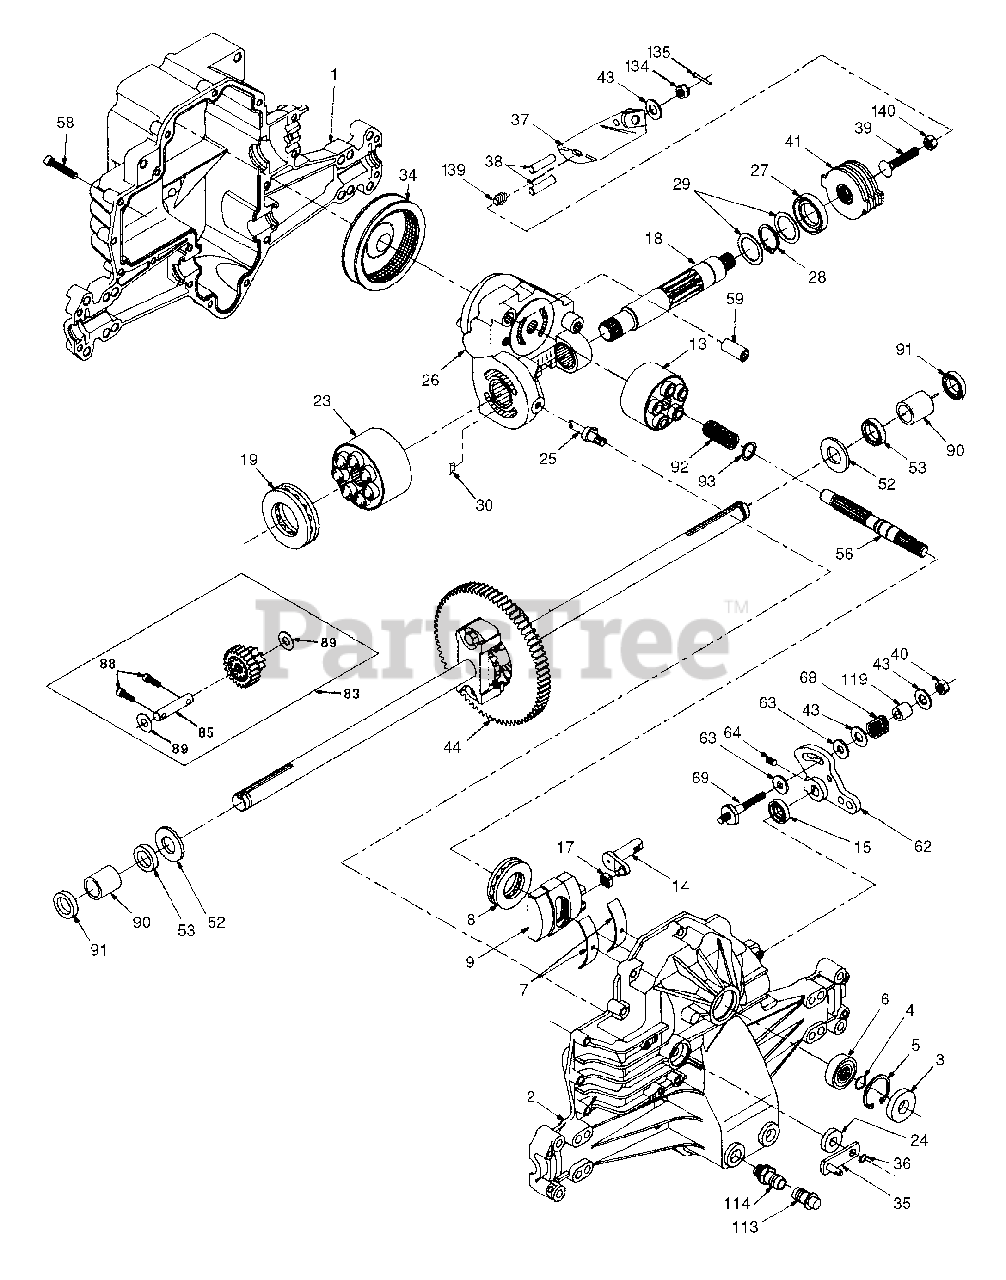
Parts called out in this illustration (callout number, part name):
1	Housing, Lower
2	Assembly, Upper Housing
3	Seal, Lip
4	Ring, Wire Retaining
5	Ring, Retaining
6	Bearing, Shaft Ball
7	Bearing, Cradle
8	Bearing, Thrust 30 x 52 x 13
9	Swashplate, Variable
13	Block, Cylinder Assembly
14	Arm, Trunnion
15	Seal, Lip
17	Guide, Slot
18	Shaft, Motor
19	Bearing, Thrust 42 x 68 x 16
23	Block, Cylinder Assembly
24	Seal, Lip 10 x 25 x 7
25	Actuator, Bypass
26	Center Section Assembly Kit
27	Seal, Lip 26 x 42 x 8
28	Ring, Retaining
29	Washer 26 x 35 x 1
30	Plate, Bypass
34	Oil Filter Element
35	Arm, Bypass
36	Ring, Retaining
37	Arm, Actuating
38	Pin, Actuating
39	Bolt 5/16-24 x 1-3/4
40	Locknut, Hex 5/16-24 UNJC
41	Brake Rotor/Stator Kit
43	Washer 7/16 x 7/8 x .060
44	Differential Assembly
52	Washer 3/4 x 1.5 x .13
53	Seal .75 x 1.25 x .250
56	Shaft, Input
58	Bolt 1/4-20 x 1.38
59	Pin .5 OD x .43 ID x .750
62	Arm, Control
63	Puck, Dampener
64	Set Screw
68	Spring
69	Stud 5/16-24
83	Jackshaft Assembly
85	Jackshaft
88	Screw, Cap
89	Washer 7/16 x 1 x 1/2
90	Sleeve Bearing
91	Seal, Wiper
92	Spring, Block
93	Washer, Block Thrust
113	Cap, Vent Assembly
114	Fitting, O-Ring Assembly
119	Spacer
134	Nut, Castle 5/16-24
135	Pin, Cotter
139	Spring, Compression
140	Nut, Hex 5/16-24
